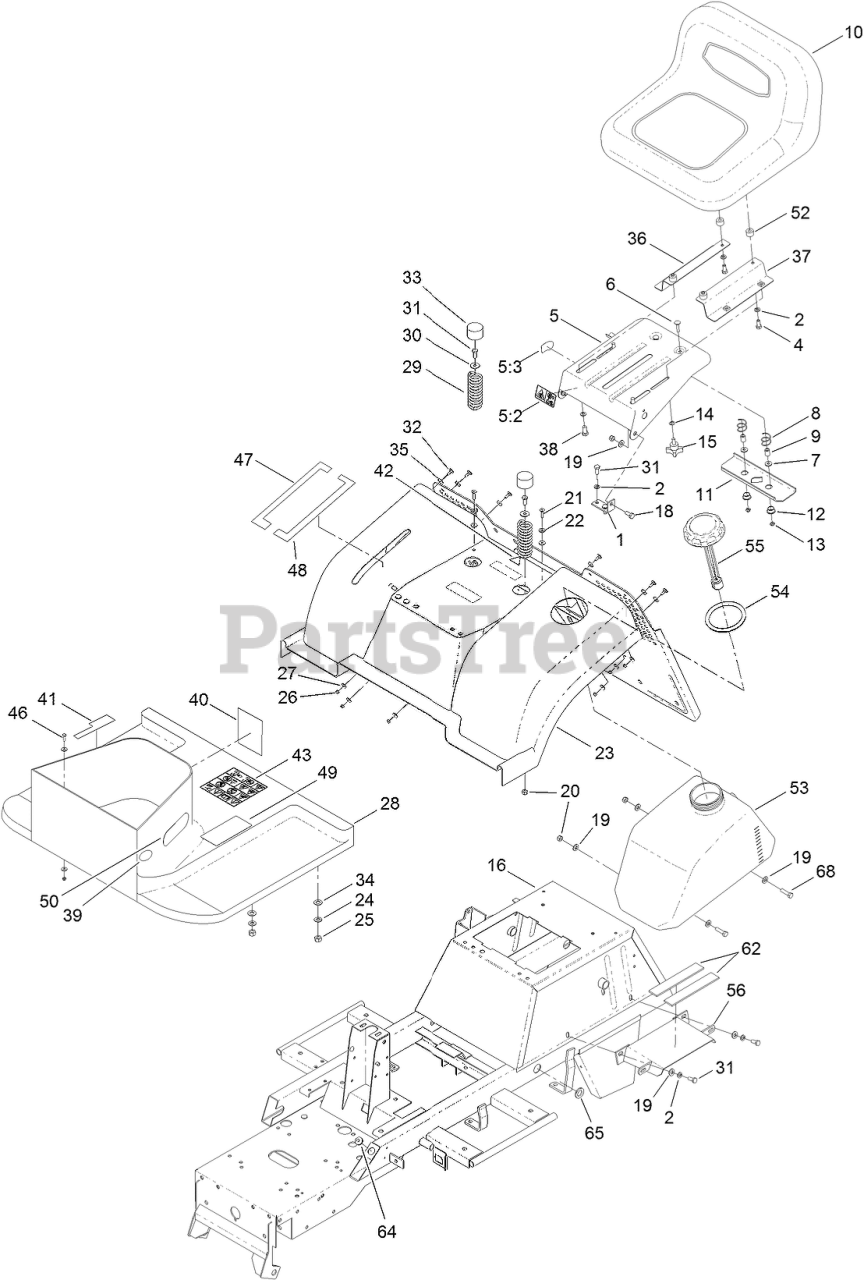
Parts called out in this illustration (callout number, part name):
1	BRACKET-SUPPORT, SEAT
2	WASHER-LOCK
4	SCREW-HH
5	SEAT PAN ASM
5:2	DECAL-DANGER
5:3	DECAL-SWITCH
6	BOLT-CARRIAGE
7	WASHER-FLAT
8	SPRING-SEAT
9	SPACER-SPLIT
10	SEAT ASM
11	BRACKET
12	BUSHING
13	NUT-LOCK
14	WASHER-SPRING
15	KNOB-ADJUSTMENT
16	FRAME KIT
18	SCREW-SUPPORT, SEAT
19	WASHER-PLAIN
20	NUT-LOCK, NI
21	SCREW-HSFH
22	WASHER-FINISH
23	FENDER-REAR
24	WASHER-FLAT
25	NUT-LOCK, NI
26	NUT-LOCK
27	WASHER-FLAT
28	FOOTREST ASM
29	SPRING-SEAT
30	WASHER-PLAIN
31	SCREW-HH
32	BOLT-CARRIAGE
33	CAP-HUB
34	WASHER-RUBBER
35	WASHER-RUBBER
36	BRACKET-SEAT, RH
37	BRACKET-SEAT, LH
38	SCREW-HHF
39	DECAL-BRAKE, PARKING
40	DECAL-STARTING
41	DECAL-OPERATION, HYDRO
42	DECAL-BAG TO FRAME
43	DECAL-DANGER
46	SCREW-HH
47	DECAL-HOC, LH
48	DECAL-HOC, RH
49	DECAL-OPERATION
50	DECAL-TOWER
52	SHIM-SEAT
53	TANK-FUEL
54	PROTECTOR-NECK, FILLER
55	CAP-FUEL
56	BRACKET-TANK, FUEL
62	STRIP-RUBBER, FUEL TANK
64	GROMMET
65	GROMMET
68	SCREW-HH
